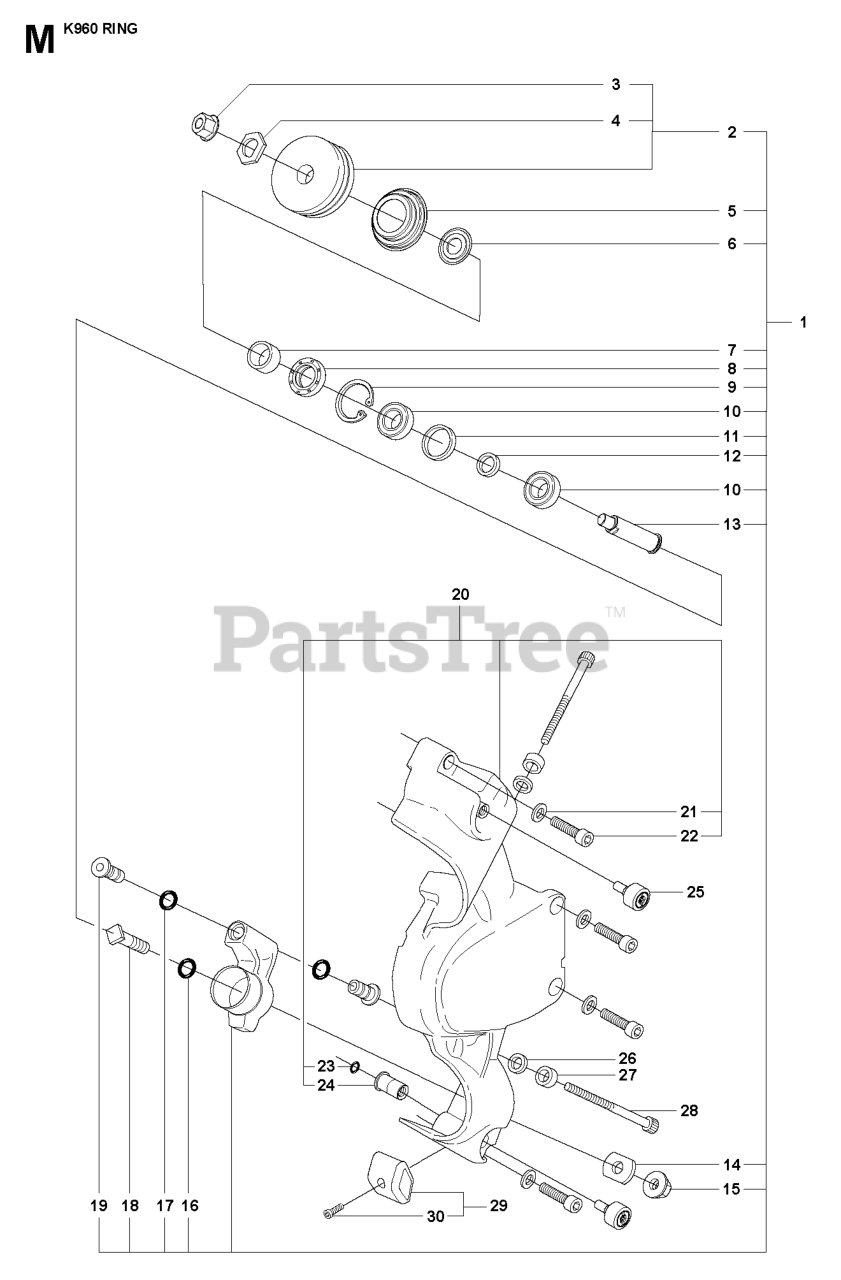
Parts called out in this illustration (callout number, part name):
2	SUPPORT ROLLER
3	NUT W/ WASHER
9	RETAINING RING SGH 28
10	BEARING
15	NUT M8 FLANGE
21	WASHER LOCK 8.7X13.5X2.5 ZN FL
